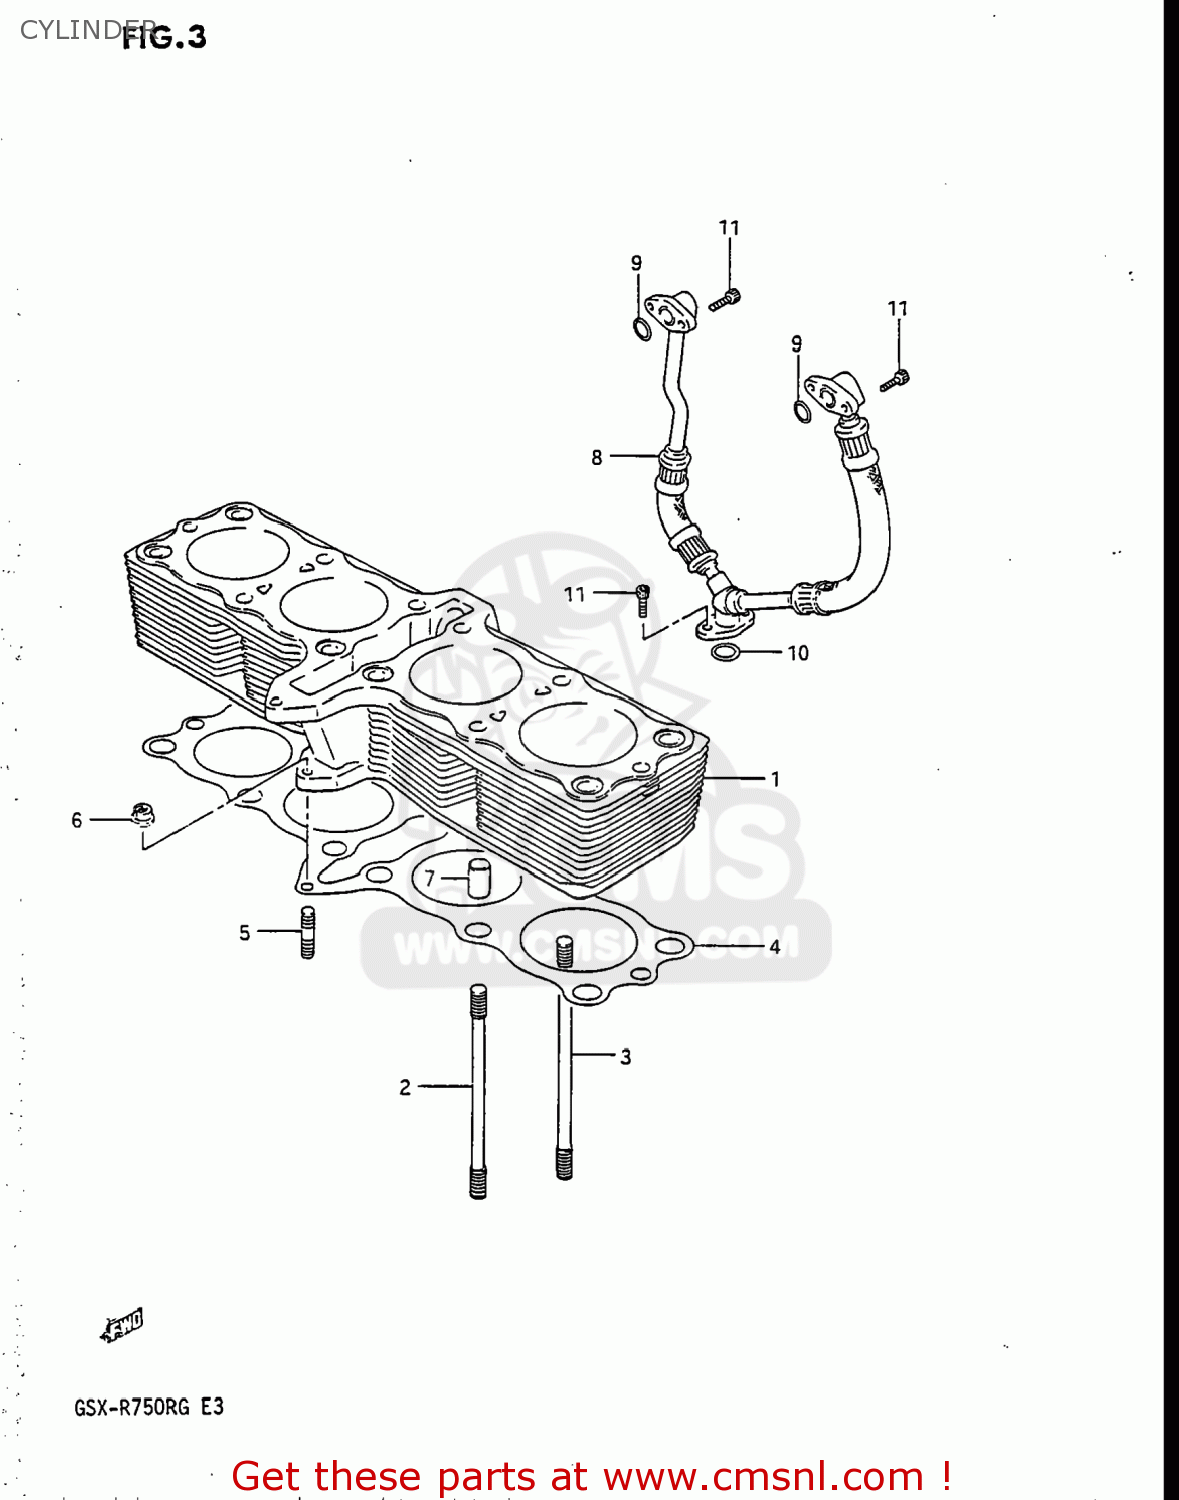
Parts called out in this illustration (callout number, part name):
1	CYLINDER
2	STUD
3	BOLT,STUD
4	GASKET,CYLINDER (NAS)
5	STUD BOLT L:20
6	NUT 6MM
7	PIN
8	HOSE
9	O RING(D:2.4,ID:12.3)
10	O RING(D:2.4,ID:15.8)
11	BOLT
